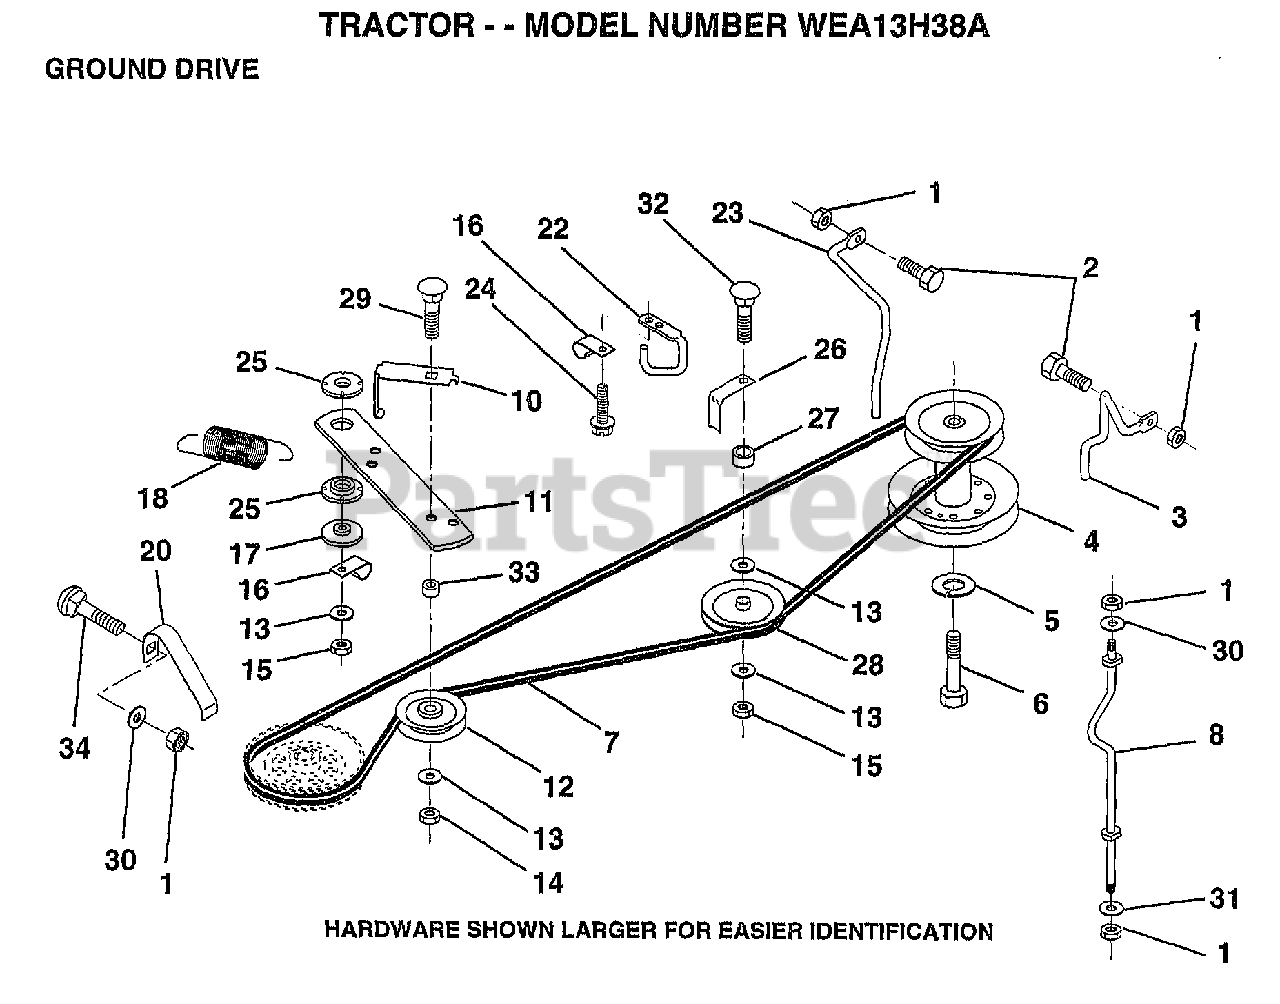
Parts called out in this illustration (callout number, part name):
1	NUT
2	BOLT
3	KEEPER.BELT.MWR.DRIVE.RH
4	PULLEY.ENGINE.LR
5	LOCKWASHER
6	HEX BOLT
7	BELT-V.DRV.77.75
8	KEEPER.BELT.HYDRO
10	KEEPER.BELT.GRD.
11	ARM-IDLER.DR.GRND
12	PULLEY.IDLER.FLAT
13	WASHER
14	LOCKNUT
16	"CLIP,INSULATOR"
17	SPACER
20	KEEPER.BELT.LH
22	"KEEPER,FRA DR BEL"
23	KEEPER.BELT.LH.FR
24	SCREW
25	BUSHING.NYLON
26	KEEPER.BELT.IDLER
27	SPACER.625X.843
28	PULLEY.IDLER.V.GR
29	BOLT RDHD 3/8-16
30	WASHER
31	WASHER M
32	BOLT
34	BOLT
